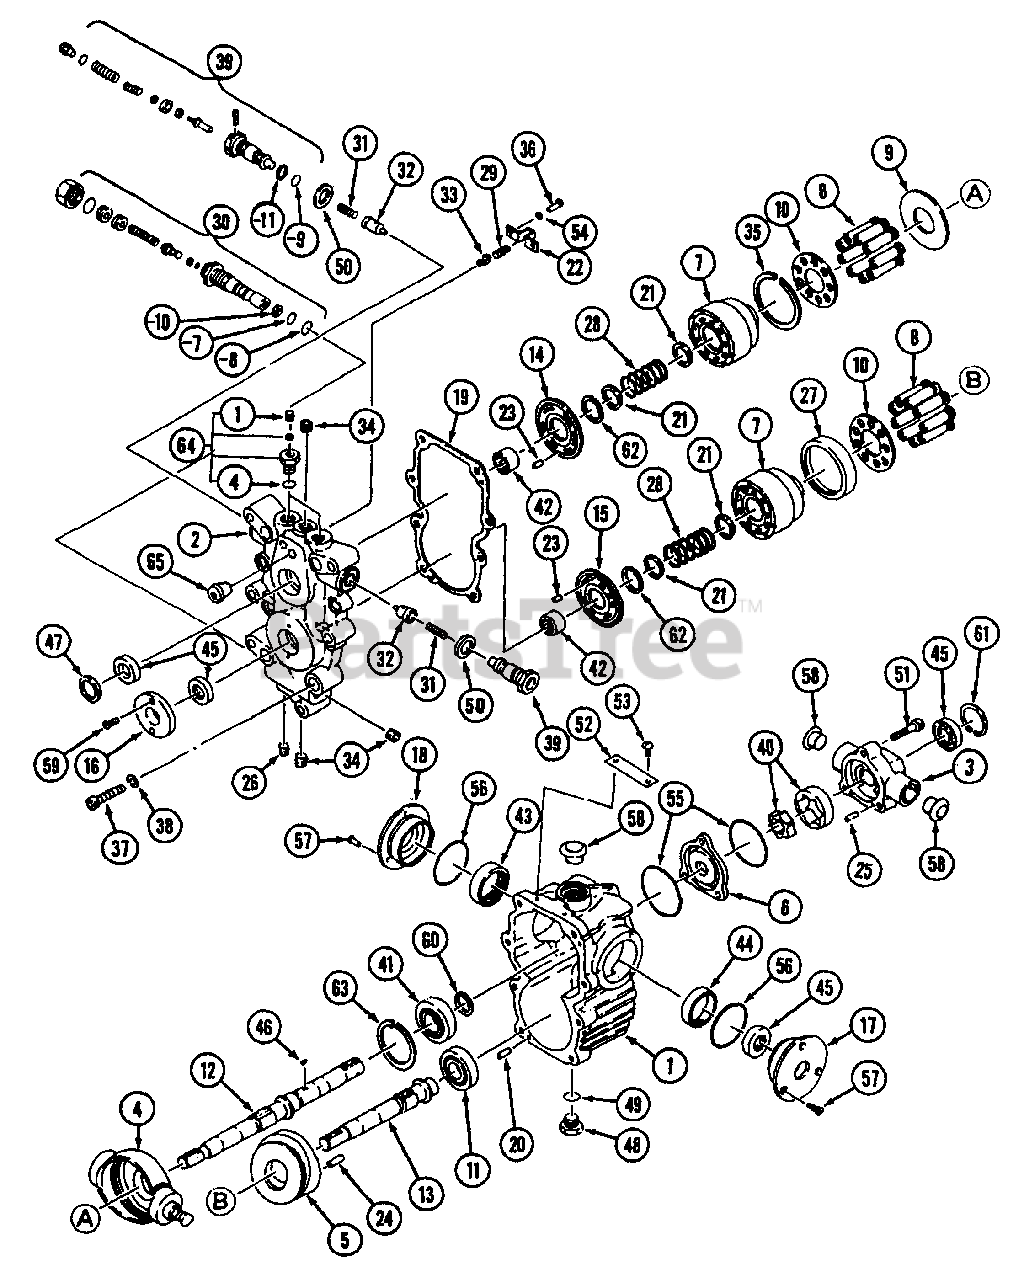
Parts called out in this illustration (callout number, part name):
3	Charge Pump Case
5	Swash Plate
7	Cylinder Block
8	Piston S/A
9	Plate, Thrust
10	Plate, Retainer
11	Bearing, Ball
17	Cover
18	Cover B
21	Holder, Spring
22	Holder, Spring
27	Holder, Retainer
28	Spring
30	Valve S/A
30-7	O-Ring
30-10	Ring, Back Up
38	Washer, Spring
39	Valve S/A
39-11	Ring, Back Up
40	Trochoid Rotor
41	Bearing, Ball
42	Bearing, Needle
43	Bearing, Needle
44	Bush
52	Plate, Name
53	Screw, Drive
54	Washer, Spring
62	Ring, Snap
64	Plug S/A
